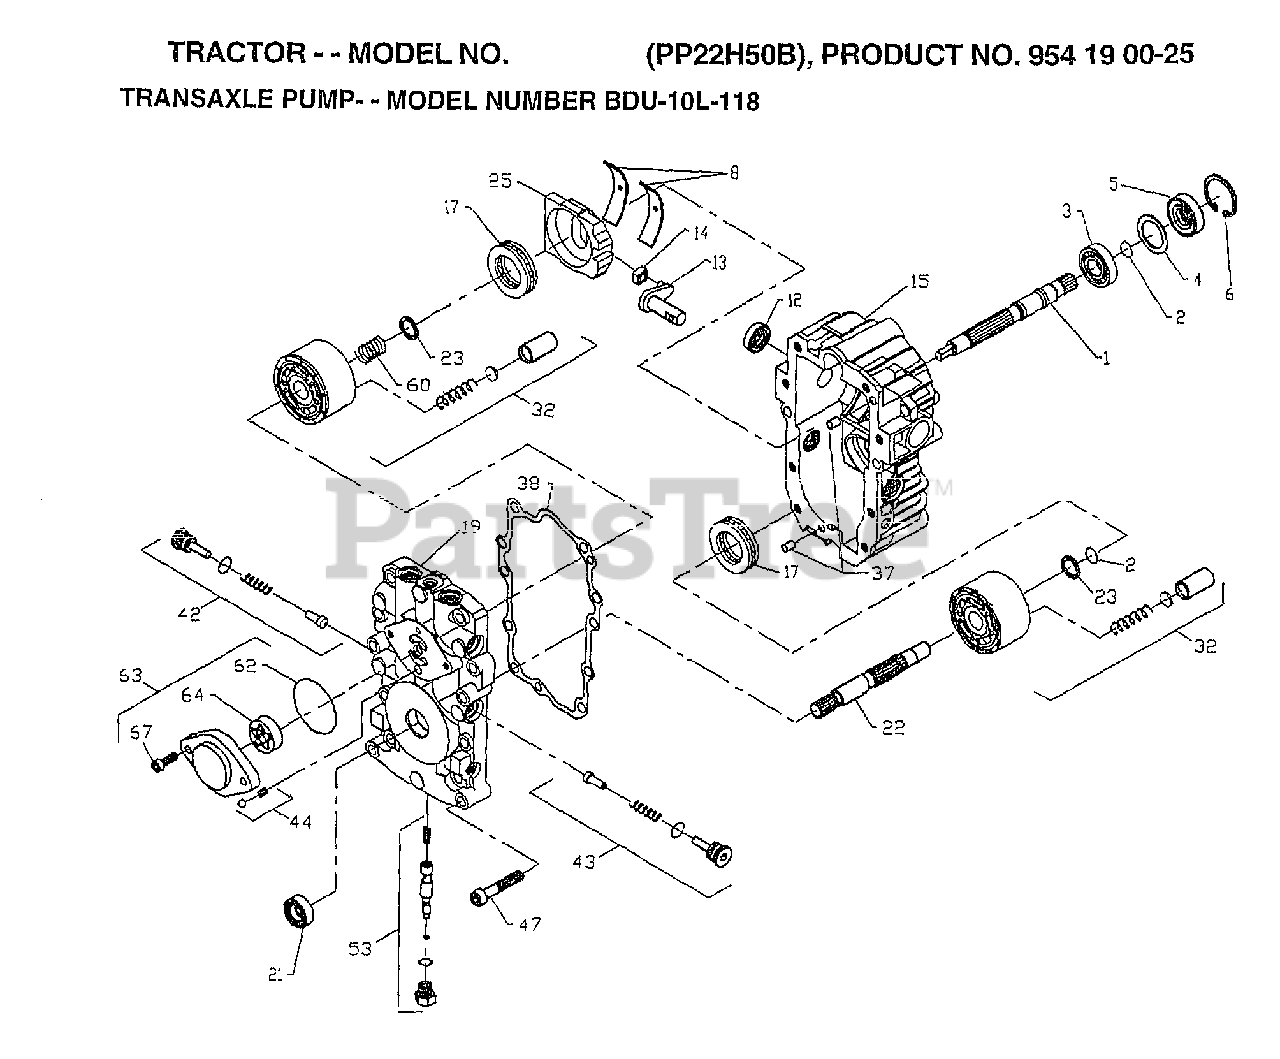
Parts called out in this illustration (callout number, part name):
1	SHAFT.PUMP.50158
2	RETAINIANG RING-(2003016)
3	BALL BEARING
4	SPACER
5	SEAL LIP
6	RING.RET.2003052
8	CRADLE BEARING (2003023)
12	SEAL.9008000-0126
13	TRUNION ARM (2003005)
14	GUIDE.2000015.HYD
15	KIT.HSG.2513035.
19	KIT.CENTER.50642
21	LIP SEAL-9008000-0127
22	SHAFT.MOT.2003034
23	WASHER.2003017
25	"SWASHPLATE,VARIAB"
32	BLOCK.CLYN.70079.
37	PIN
38	GASKET.20030600
42	KIT.VALVE.2510050
43	KIT.VALVE.2510050
44	KIT.RELI.2510011.
47	SCREW9007314-0808
53	"KIT,BYPASS VALVE"
60	SPRING.2003014.
62	0RING.90041011340
63	KIT.CHARG.2513027
64	GEROTOR.J1041008
67	SCREW.CAP.50095.
